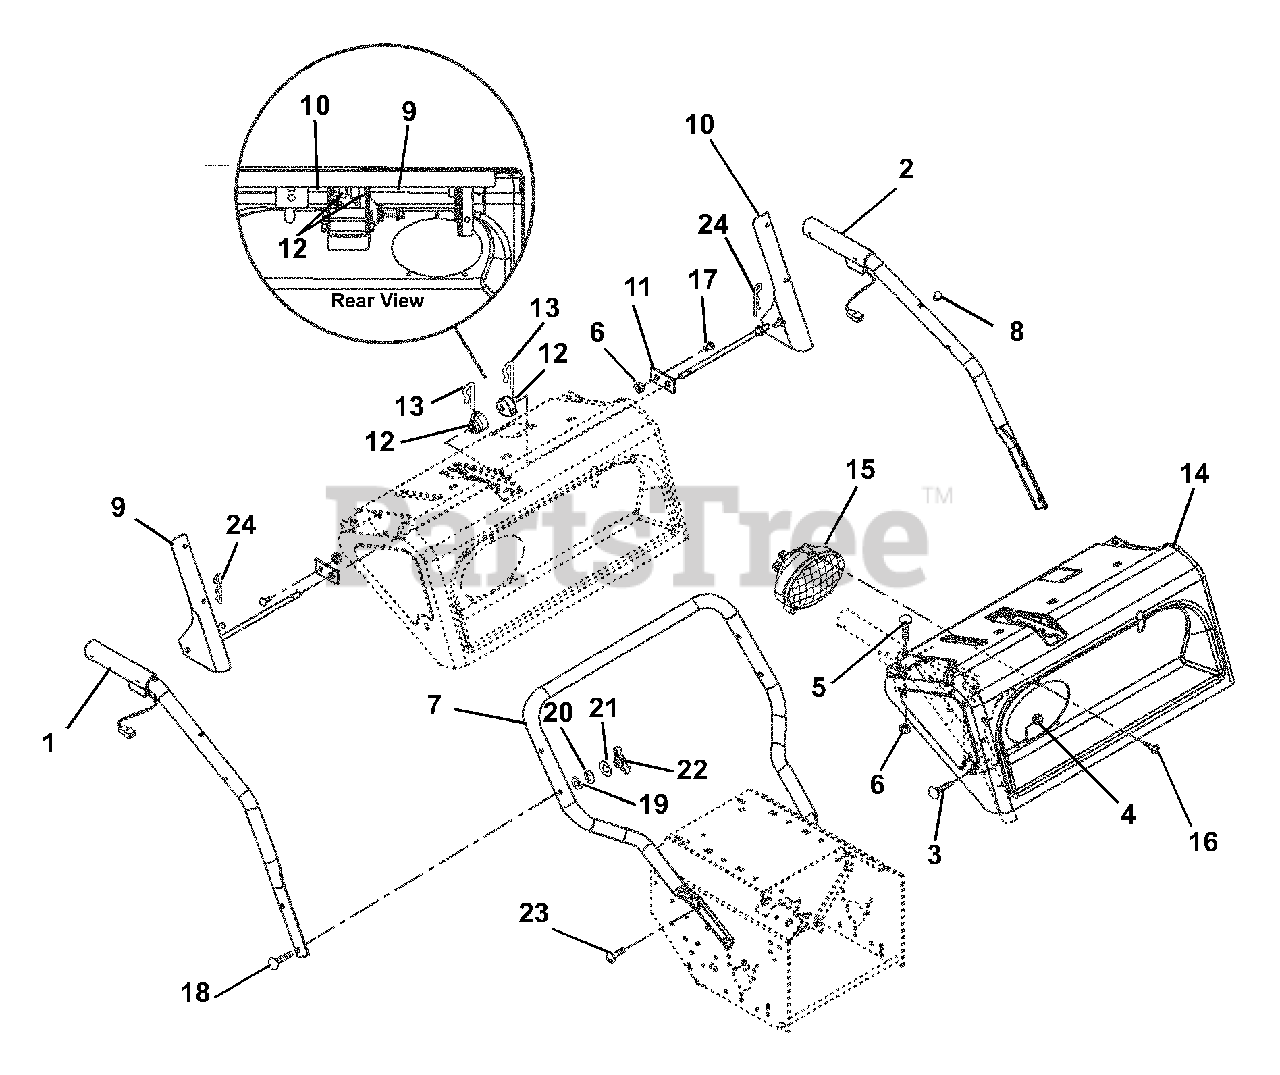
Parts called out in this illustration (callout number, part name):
1	Handlebar, Upper Right Hand
2	Handlebar, Upper Left Hand
3	Bolt, Round Head Square Neck .31-18 x 1.75 Grade 5
4	Nut, Locking Center .31-18
5	Bolt, Round Head Square Neck .25-20 x 1.25
6	Nut, Locking Center .25-20
7	Handlebar, Lower
9	Kit, Right Hand Lever with Grip
10	Kit, Left Hand Lever with Grip
11	Bracket, Retaining
12	Cam, Interlock
13	Pin, Spring Clip
14	Panel with Control Decal, Gravely 936
15	Headlamp, Oval with 1156 Bulb
16	Screw, Tapping 10-16 x .75 Hi-Lo
17	Bolt, Round Head Square Short Neck .25-20 x .50
18	Bolt, Round Head Square Neck .31-18 x 2.25
19	Washer, Saddle .32 x .94 x .062
20	Washer, Locking .31 x .097 Heavy
21	Washer, Flat Steel .38 x .875 x .083
22	Knob, Wing .31-18
23	Bolt, Screw Hex Flanged Whiz Lock Head .38-16 x .75
24	Pin-Hair #25
